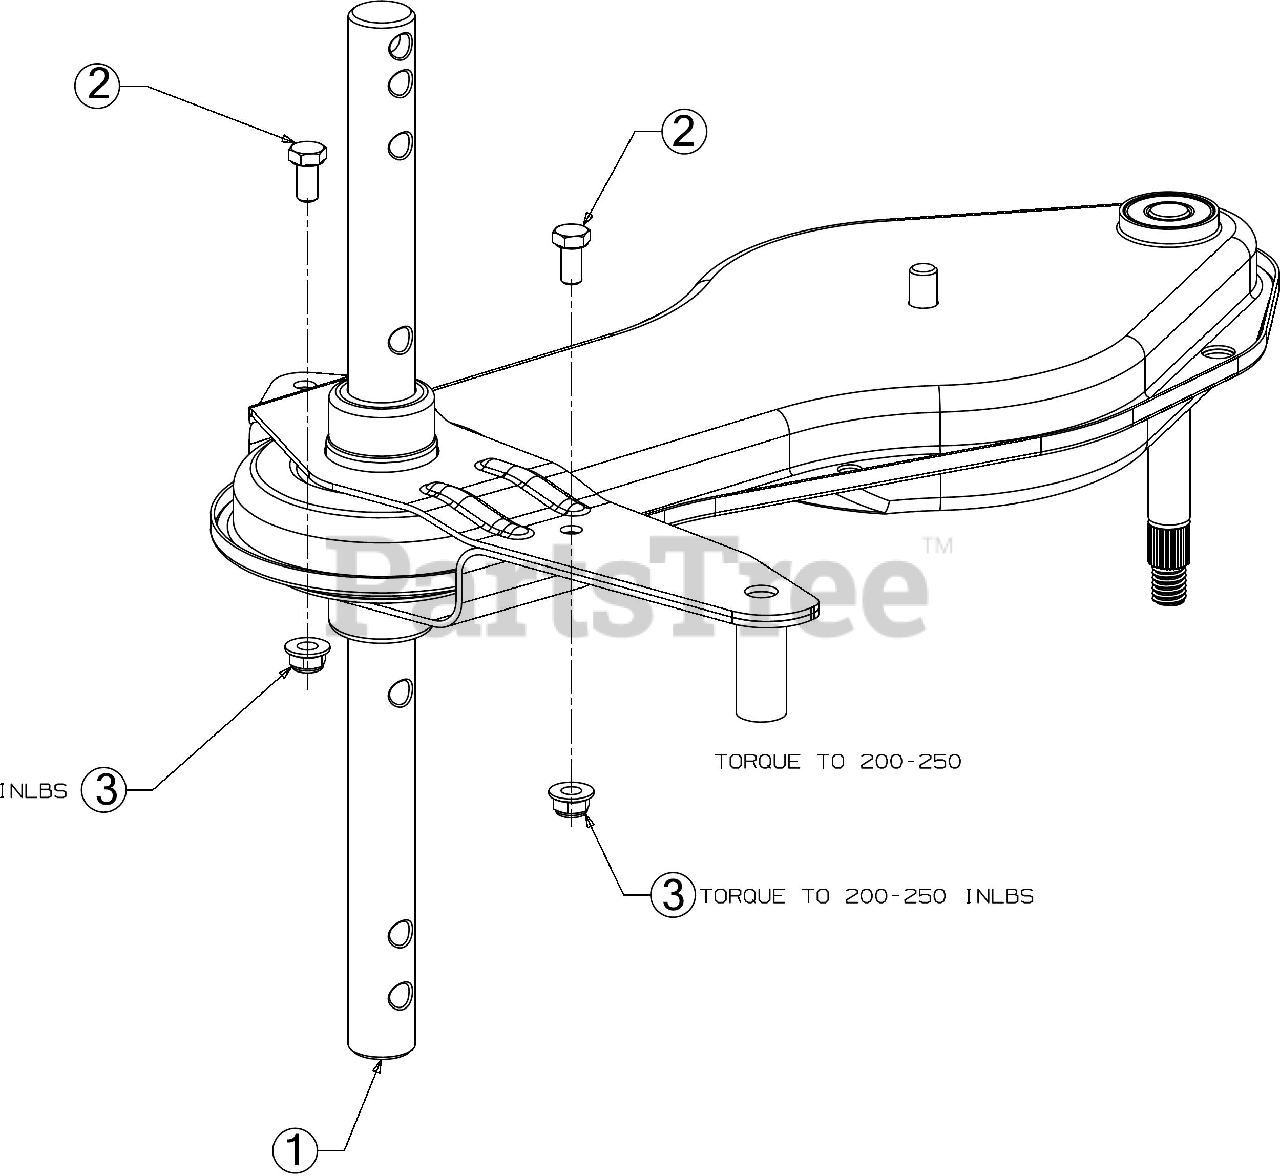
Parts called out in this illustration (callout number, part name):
1	CHAIN CASE ASSEMBLY
1	#420 CHAIN 1/2 PITCH
1	#50 CHAIN 5/8 PITCH
1	FLAT WASHER
1	GROOVE BALL BEARING
2	SCREW 5/16-18X .625 GR5
3	FLANGE LOCK NUT 5/16-18
